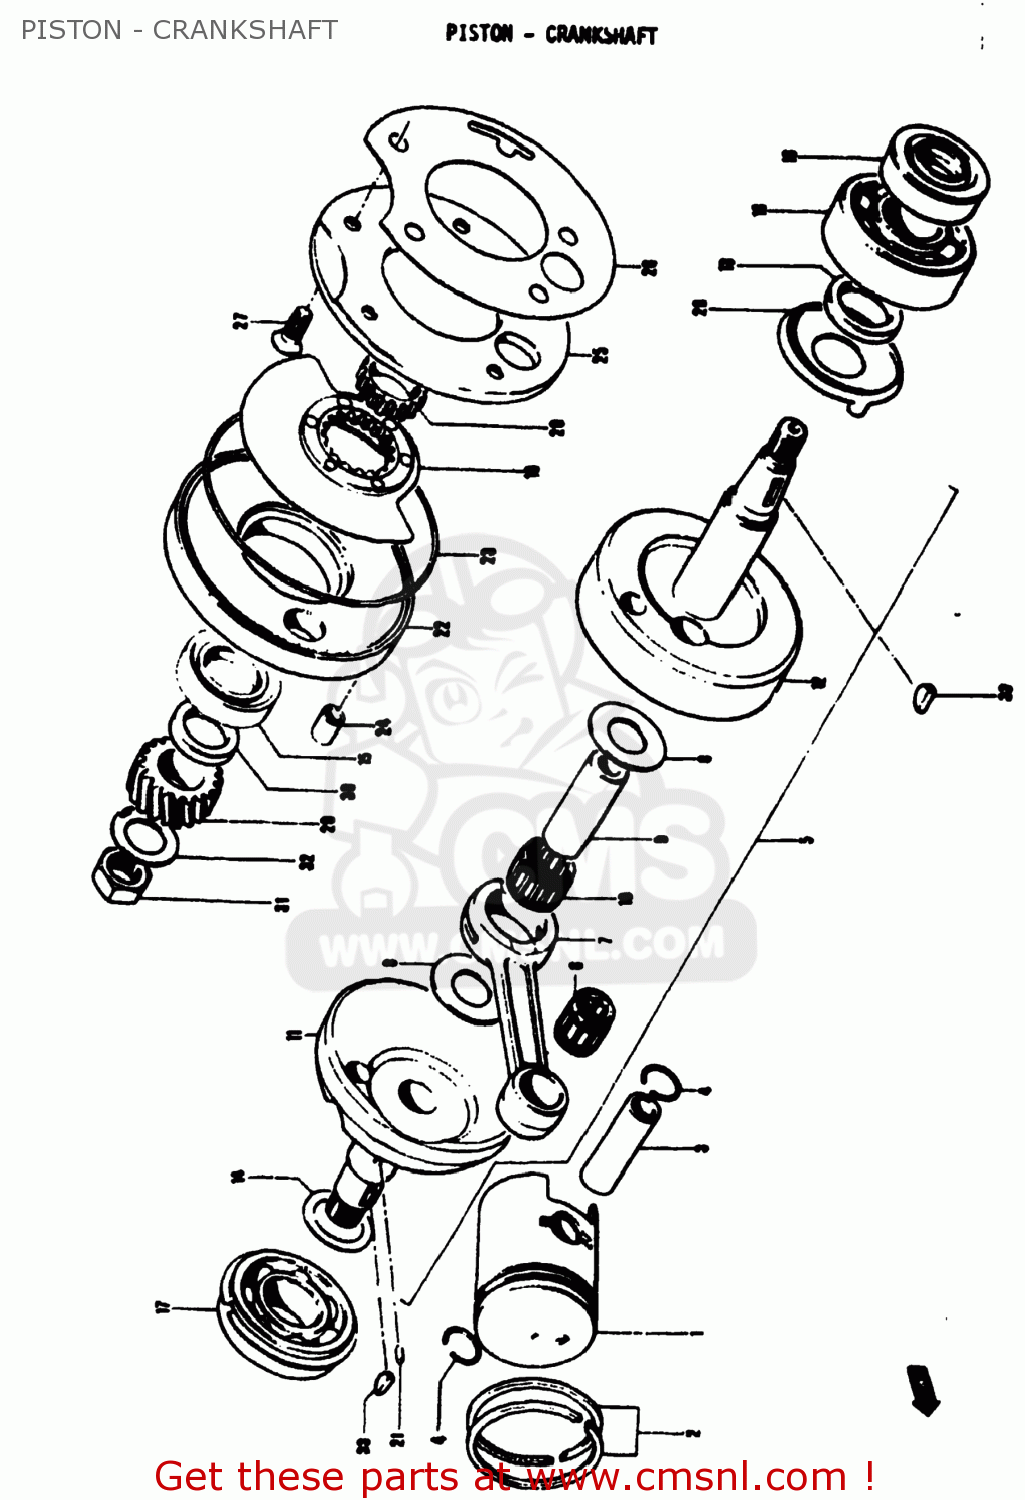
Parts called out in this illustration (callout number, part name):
1	PISTON
2	RING SET,PISTON
3	PIN,PISTON
4	RING,SNAP
5	CRANKSHAFT SET
6	BEARING
7	CONNECTING ROD
8	WASHER(16X32X1)
9	PIN,CRANK
10	BEARING
11	CRANKSHAFT
12	CRANKSHAFT,LEFT
13	SPACER(20X28X4.5)
14	THRUST WASHER
15	OIL SEAL (25X44X7)
16	OIL SEAL
17	BEARING(20X52X15)
18	BEARING(20X47X14)
19	PLATE,DISC VALVE
20	GUIDE,ROTERY VALVE
21	PIN 3X5
22	SEAT,CRANKCASE OUTER VALVE
23	O RING(D:2.4,ID:100.6)
24	PIN
25	SEAT,INNER VALVE
26	GASKET,ROTERY VALVE INNER SEAT (NAS)
27	SCREW
28	PLATE,CSHAFT OIL GUIDE
29	GEAR,PRIMARY DRIVE
30	SPACER(20X25X10)
31	NUT
32	WASHER
33	KEY
